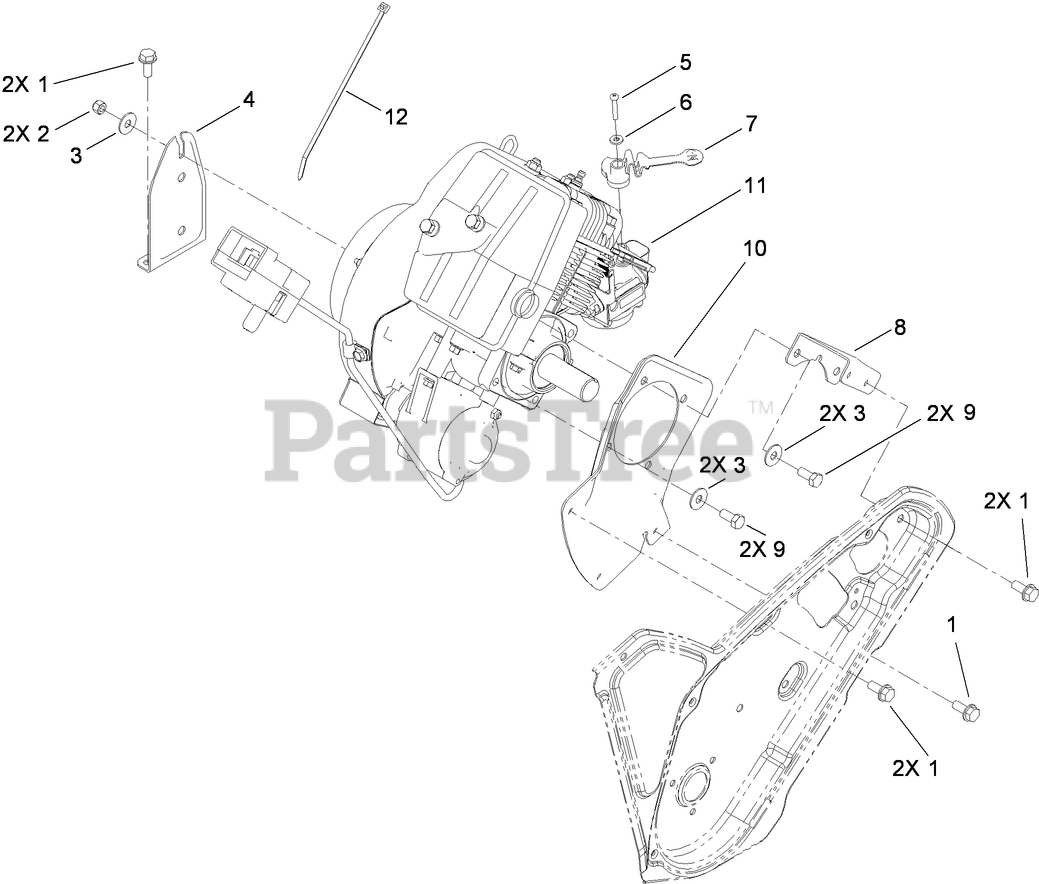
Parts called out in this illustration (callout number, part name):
1	SCREW-THD ROLL, HWH
2	NUT-LOCK, NI
3	WASHER-BELLEVILLE
4	BRACKET-RECOIL
5	SCREW-PPH, PLASTITE
6	WASHER-FLAT
7	LEVER-CHOKE
8	SUPPORT-ENGINE, SIDE
9	SCREW-HH
10	PLATE-ENGINE, PTO
12	TIE-CABLE
